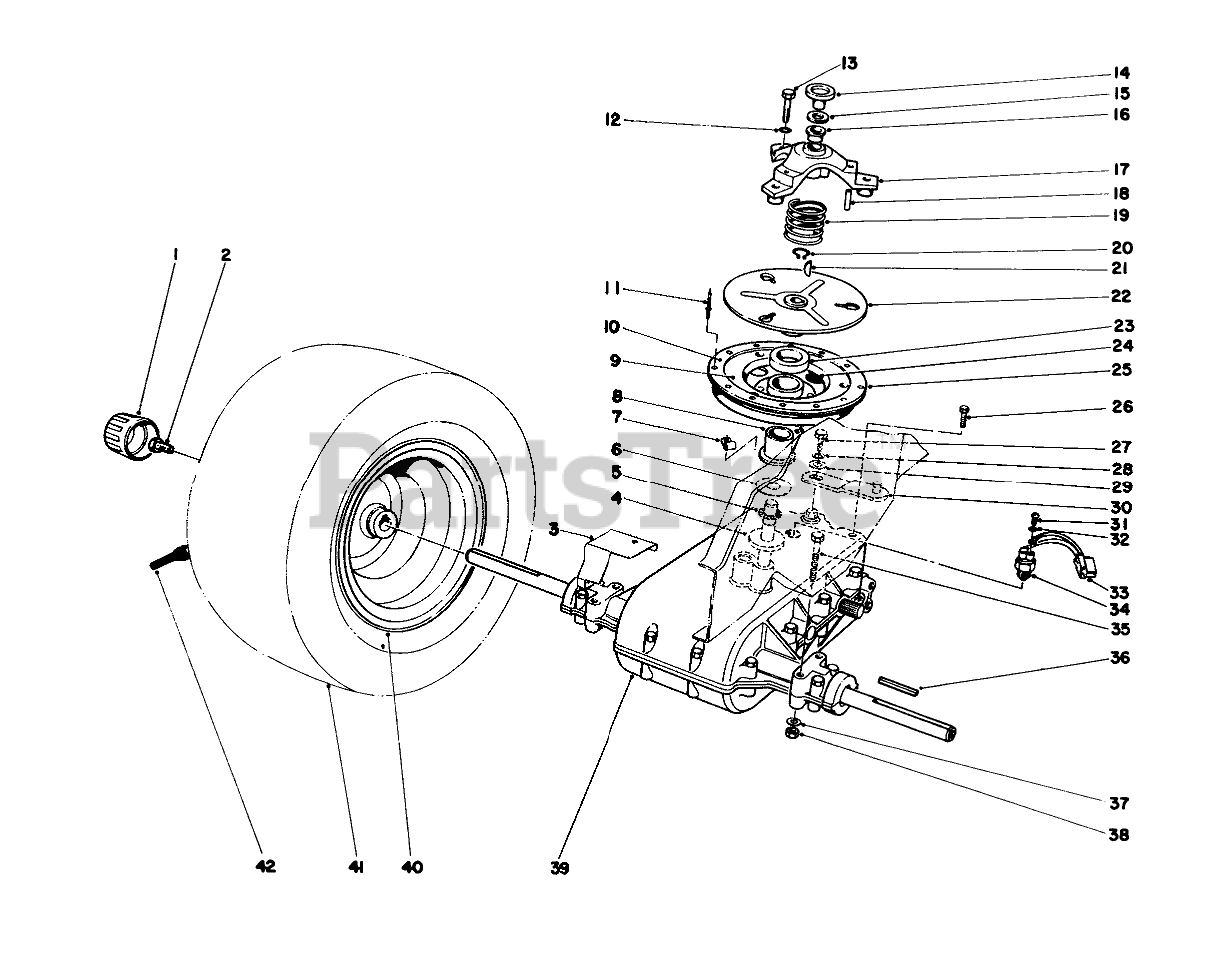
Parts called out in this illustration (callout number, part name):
1	CAP-HUB
2	CAPSCREW 3/8 16 3/4
3	GRASS SHIELD B
4	SPACER
5	NEEDLE BRG
6	THRUST WASHER
7	Clamp (Incl. with Main Wire Harness)
9	CLUTCH PAD
10	RETAINER RING R
11	RIVET
12	WASHER-LOCK
13	SCREW-HH
14	CLUTCH CAP
15	THRUST RACE
16	BUSHING-FLANGE
17	Clutch Cover Assembly (Incl. Ref. #16 & 18)
18	NEEDLE BRG
19	COMPRESSION SPRING
20	RING-SNAP, EXTERNAL
21	KEY-WOODRUFF
22	Clutch Plate
23	WASHER FELT
25	Sheave Assembly (Incl. Ref. #8-11)
26	SCREW-HWHTF
27	SCREW-HH
28	WASHER-LOCK
29	WASHER-FLAT
30	SHIFT LEVER WA B
31	SCREW
32	WASHER-LOCK/INT
33	WIRE HARNESS
34	NEUTRAL SWITCH
35	SCREW-HH
37	WASHER-PLAIN
38	NUT-LOCK, NI
39	TRANSAXLE
40	REAR WHEEL ASSEMBLY
41	REAR TIRE
42	STEM-VALVE
